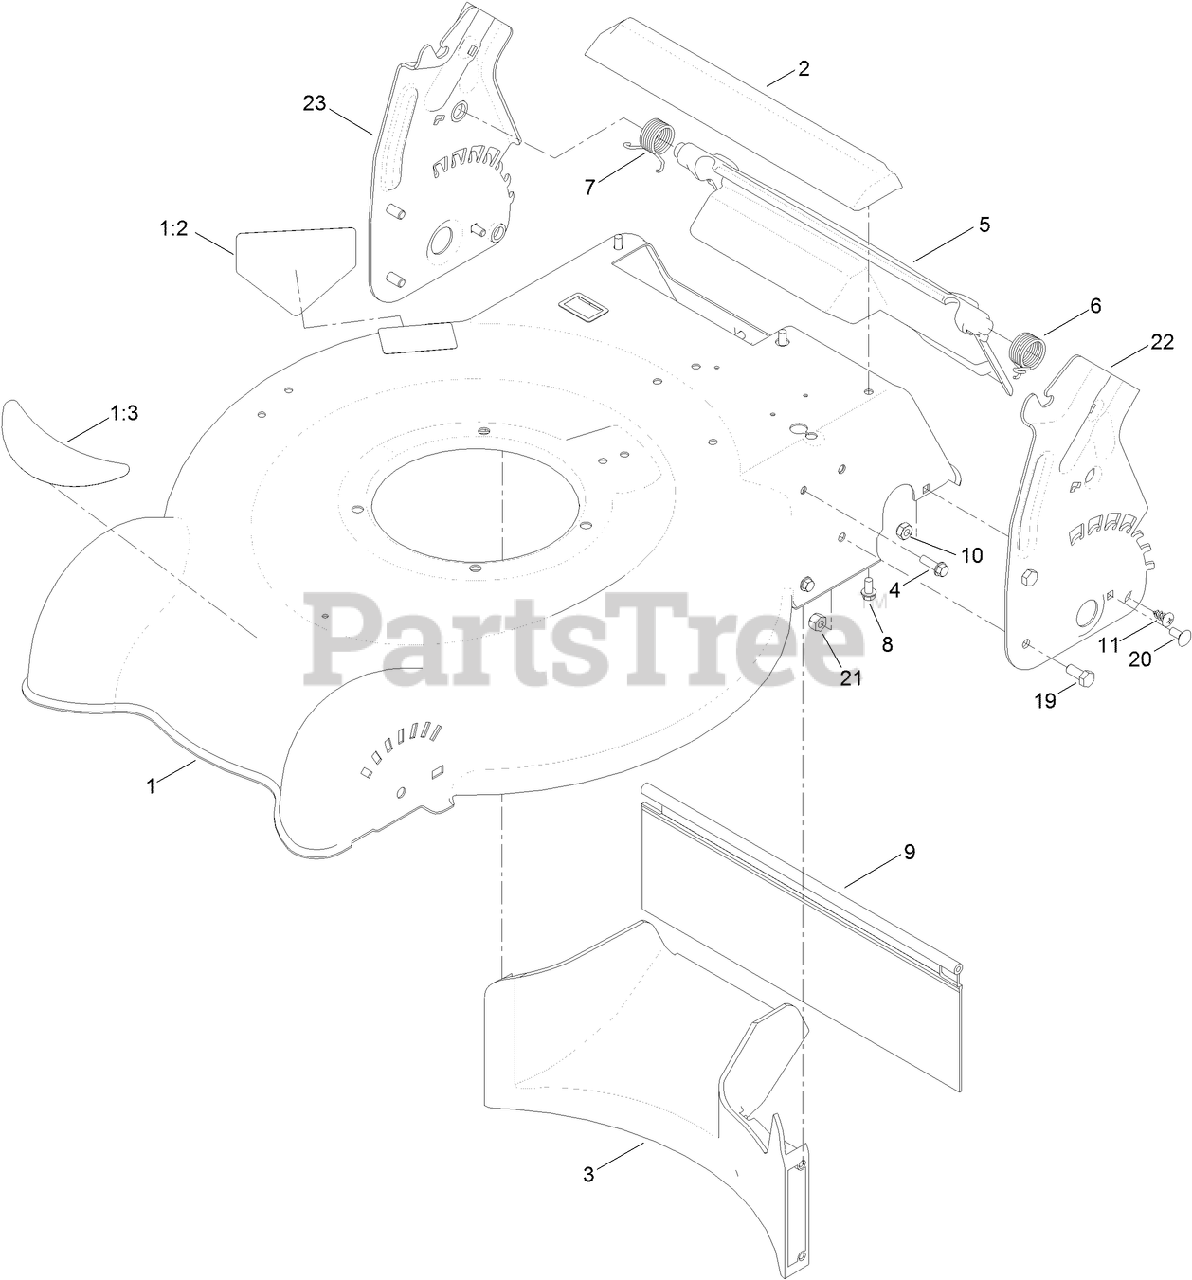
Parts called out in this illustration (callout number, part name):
1	HOUSING ASM
1:2	DECAL-DANGER
1:3	DECAL-DECK
2	CHUTE-REAR
3	BAFFLE-REAR
4	SCREW-HWH
5	REAR DEFLECTOR ASM
6	SPRING-TORSION, LH
7	SPRING-TORSION, RH
8	SCREW-PLASTITE
9	SHIELD-TRAILING
10	NUT-LOCK, NI
11	SCREW-PTH
19	SCREW-HH
20	SCREW-CARR
21	NUT-LOCK, NI
22	PLATE-HOC, LH
23	PLATE-HOC, RH
